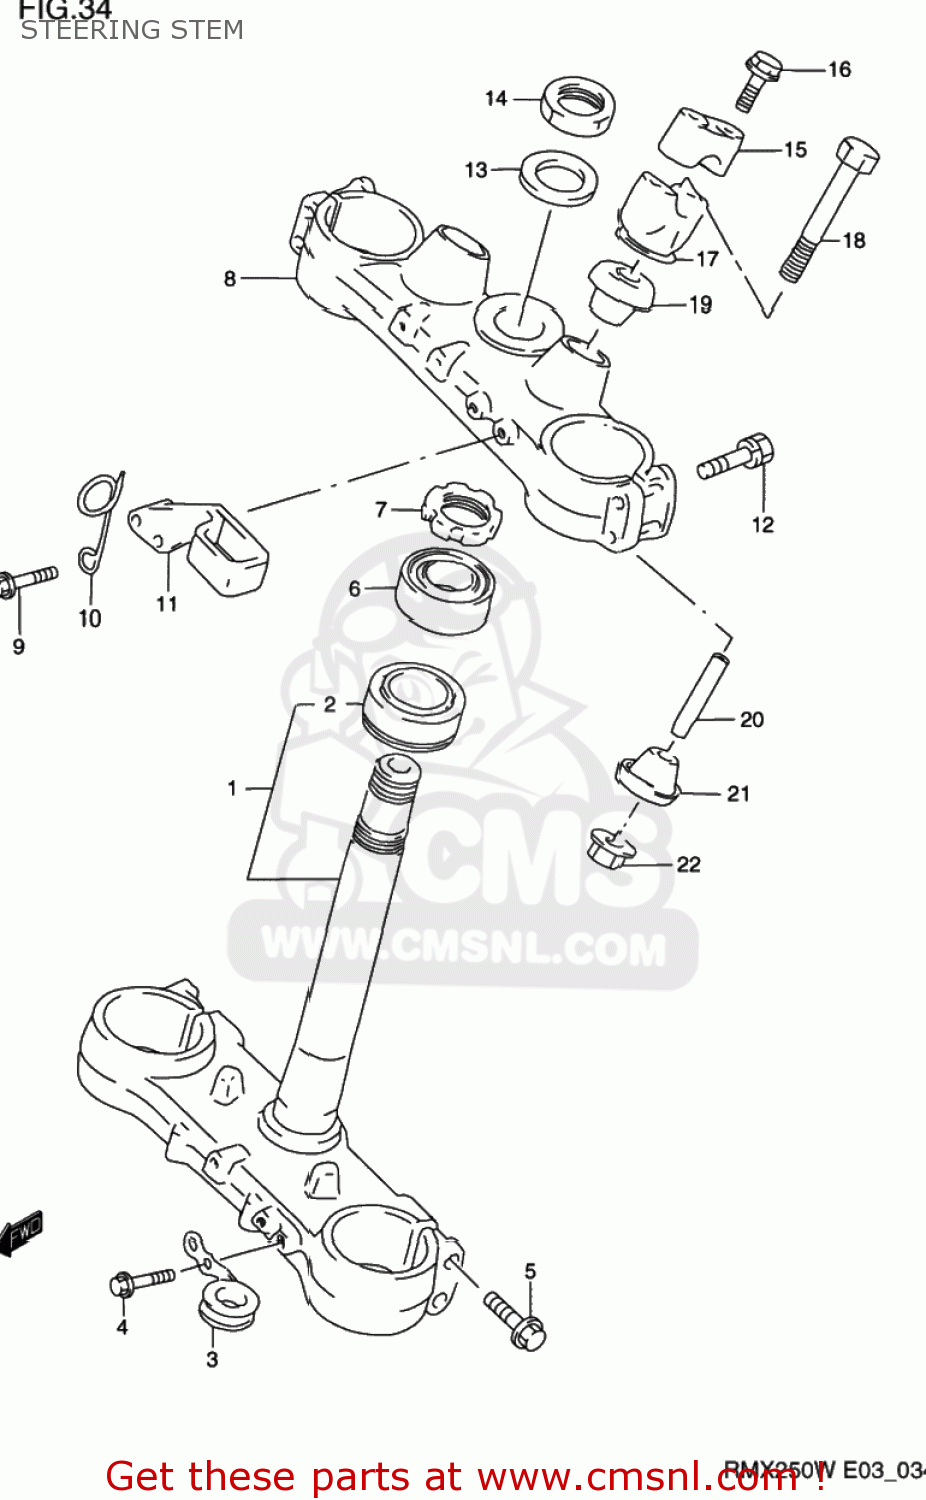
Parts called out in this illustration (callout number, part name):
1	STEM,STEERING
2	BEARING(30X52X16)
3	GUIDE,CABLE LWR
4	BOLT,PROTECTOR(6X10)
5	BOLT
6	BEARING(30X52X16)
7	NUT,STEERING
8	HEAD,STEERING STEM
9	BOLT,GUIDE
10	GUIDE,CLUTCH CABLE
11	GUIDE,HOSE
12	BOLT
13	WASHER,STEM HEAD
14	NUT,STEM HEAD
15	HOLDER,HANDLEBAR
16	BOLT,HANDLE HOLDER(8X35)
17	HOLDER,HANDLE UNDER
18	BOLT,HANDLE HOLDER(10X70)
19	CUSHION,RUBBER UPR
20	SPACER
21	CUSHION,RUBBER UNDER
22	NUT
